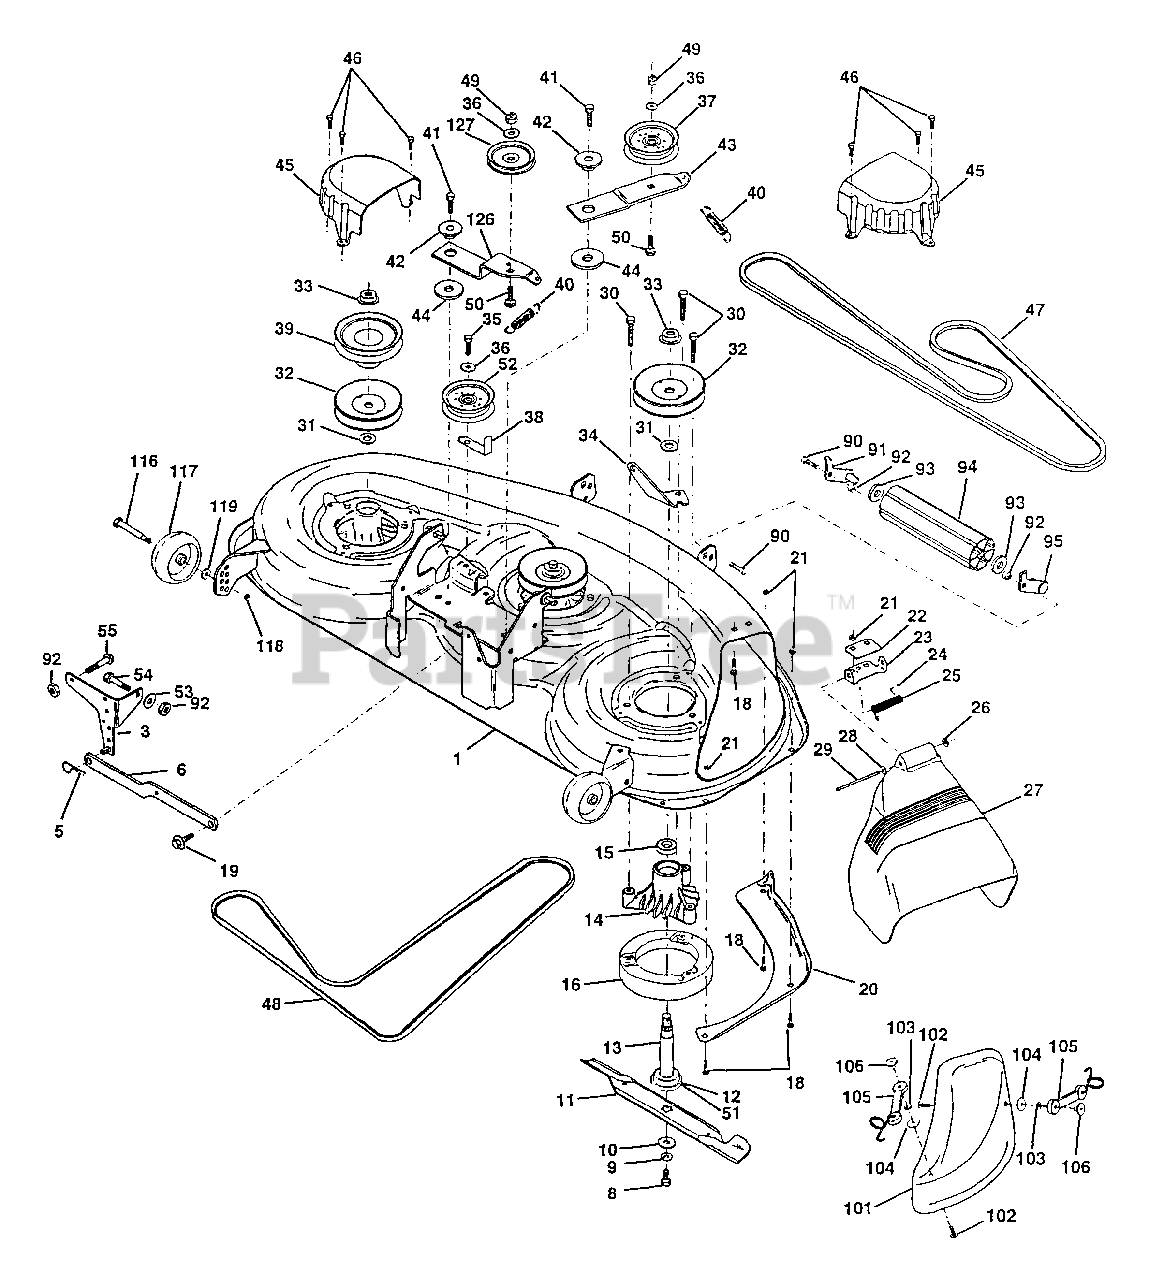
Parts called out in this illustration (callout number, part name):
1	Deck Asm., Mower 46"
3	Bracket Asm., Sway Bar
5	Retainer Spring (AYP part number)
6	Arm, Suspension, Rear (Sway Bar) (AYP part number)
8	Bolt, Patched 3/8-24 x 1-1/4 Gr. 8
9	Washer, Lock Hvy., Unplated 3/8 (AYP part number)
10	Washer, Hard Blade, Mower Vented
11	Blade, 46" Mower Deck
12	Bearing, Bail, Mandrel #6204
13	Shaft Asm. w/Lower Bearing
14	Housing, Mandrel
15	Bearing, Ball, Mandrel
16	Stripper, Mower Round (AYP part number)
18	Bolt, Carriage 5/16-18 x 5/8
19	Bolt, Hex Head, Shoulder 5/16-18
20	Baffle, Vortex Mower 46"
21	Nut, Crownlock 5/16-18 UNC
22	Stiffener, Bracket (AYP part number)
23	Bracket, Deflector (AYP part number)
24	Cap, Sleeve
25	Spring, Torsion, Deflector
26	Nut, Push
27	Shield, Deflector Mower
28	Washer 11/32 x 5/8 x 16 Ga.
29	Rod, Hinge
30	Screw, Hex Head, Thdroll (AYP part number)
31	Washer, Spacer Mower Vented (AYP part number)
32	Pulley, Mandrel (AYP part number)
33	Nut, Flg. Top Lock Cntr. 9/16
34	Anchor, Spring Deck 46"
35	Screw, Thdroll 3/8-16 x 1-3/4 Tytt
36	Washer 13/32 x 13/16 x 16 Ga.
37	Pulley, Idler, Flat (AYP part number)
38	Keeper, Belt, Idler
39	Pulley, Idler, Driven
40	Spring, Secondary 44/46/50 Vent
41	Screw, Thdroll 3/8-16 x 1-1/4 Tytt
42	Spacer, Retainer
43	Arm, Idler Secondary
44	Washer, Hardened (AYP part number)
45	Cover, Mandrel Deck
46	Screw, Thdroll. 1/4-20 x 5/8
47	V-Belt, Mower, Secondary
48	V-Belt, Mower, Primary
49	Nut, Crownlock 3/8-16 UNC
50	Bolt, Carriage 3/8-16 x 1-1/2 Gr. 5
51	Washer, Felt
52	Pulley Idler 46 Pri. Drive (AYP part number)
53	Washer 13/32 x 13/16 x 12 Ga.
54	Bolt Fin Hex 3/8-16 unc x 1 Gr. 5
55	Bolt Rdhd Sqnk 3/8-16 unc x 1 (AYP part number)
90	Bolt, Fin, Hex 3/8-16 UNC x 1
91	Bracket, Asm Noseroller, LH (AYP part number)
92	Nut, Lock, Hex w/Ins 3/8-16 UNC
93	Washer 17/32 x 7/8 x 16 Ga.
94	Roller, Nose 38 & 42 (AYP part number)
95	Bracket, asm Noseroller RH (AYP part number)
101	Cover, Mulching
102	Screw (AYP part number)
103	Washer, Lock #10
104	Washer
105	Latch Asm. Bagger
106	Nut, Weld
116	Bolt, Shoulder
117	Gauge Wheel
118	Nut, Centerlock 3/8-16 UNC
119	Washer 3/8 x 7/8 x 14 Ga.
126	Arm, Idler, Primary Deck 46"
127	Pulley, Idler, V-Groove Dim. 4.25
